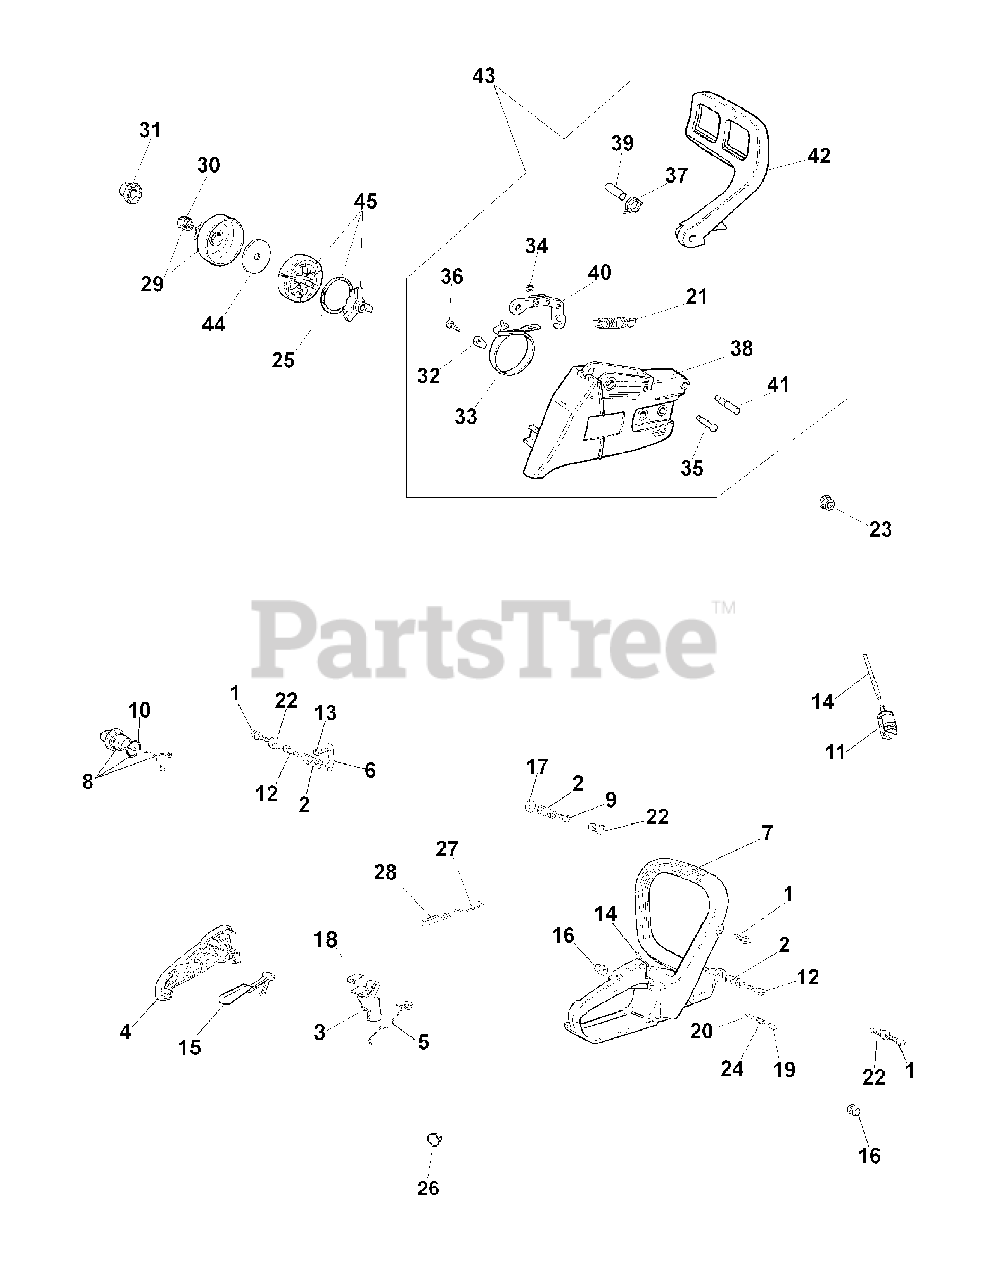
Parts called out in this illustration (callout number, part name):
3	THROTTLE LEVER
4	HANDLE COVER.
5	SPRING
15	LEVER
16	ANNULAR BUFFER
19	TANK BREATHER
20	TANK BREATHER
22	SCREW GUIDE
25	CLUTCH SPRING
27	THROTTLE ROD
28	KNOB
29	CLUTCH DRUM
31	WORM GEAR 3/8"
38	CHAIN COVER
43	CHAIN COVER
45	COMPL.CLUTCH
